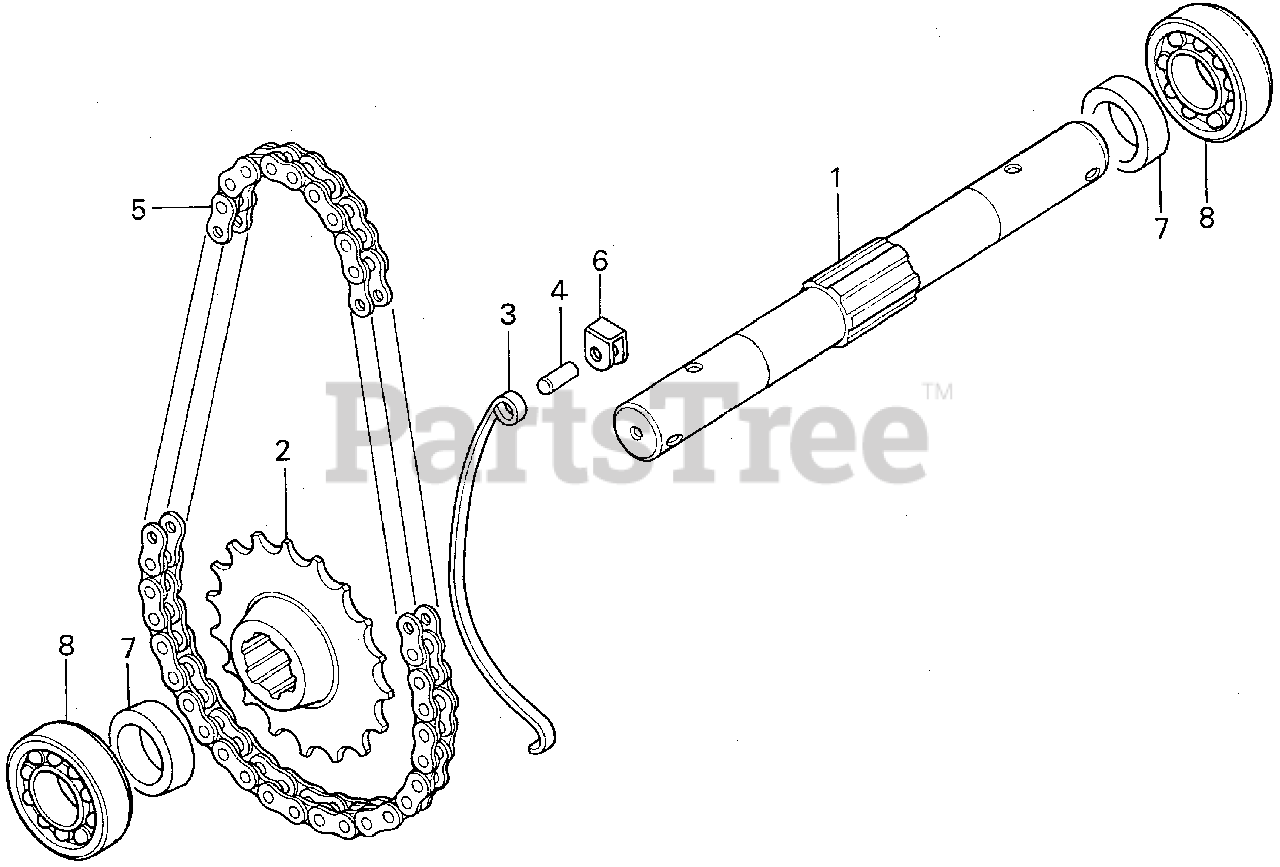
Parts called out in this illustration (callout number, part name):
1	SHAFT, WHEEL
2	SPROCKET, DRIVEN
2	SPROCKET, DRIVEN (18T)
3	TENSIONER, CHAIN (NOT AVAILABLE)
4	SHAFT, TENSIONER (NOT AVAILABLE)
4	SHAFT, TENSIONER
5	CHAIN, FINAL (RK520KFX44LE)
6	SPACER, CHAIN TENSIONER
7	COLLAR, WHEEL SHAFT
8	BEARING, RADIAL BALL (6007)
